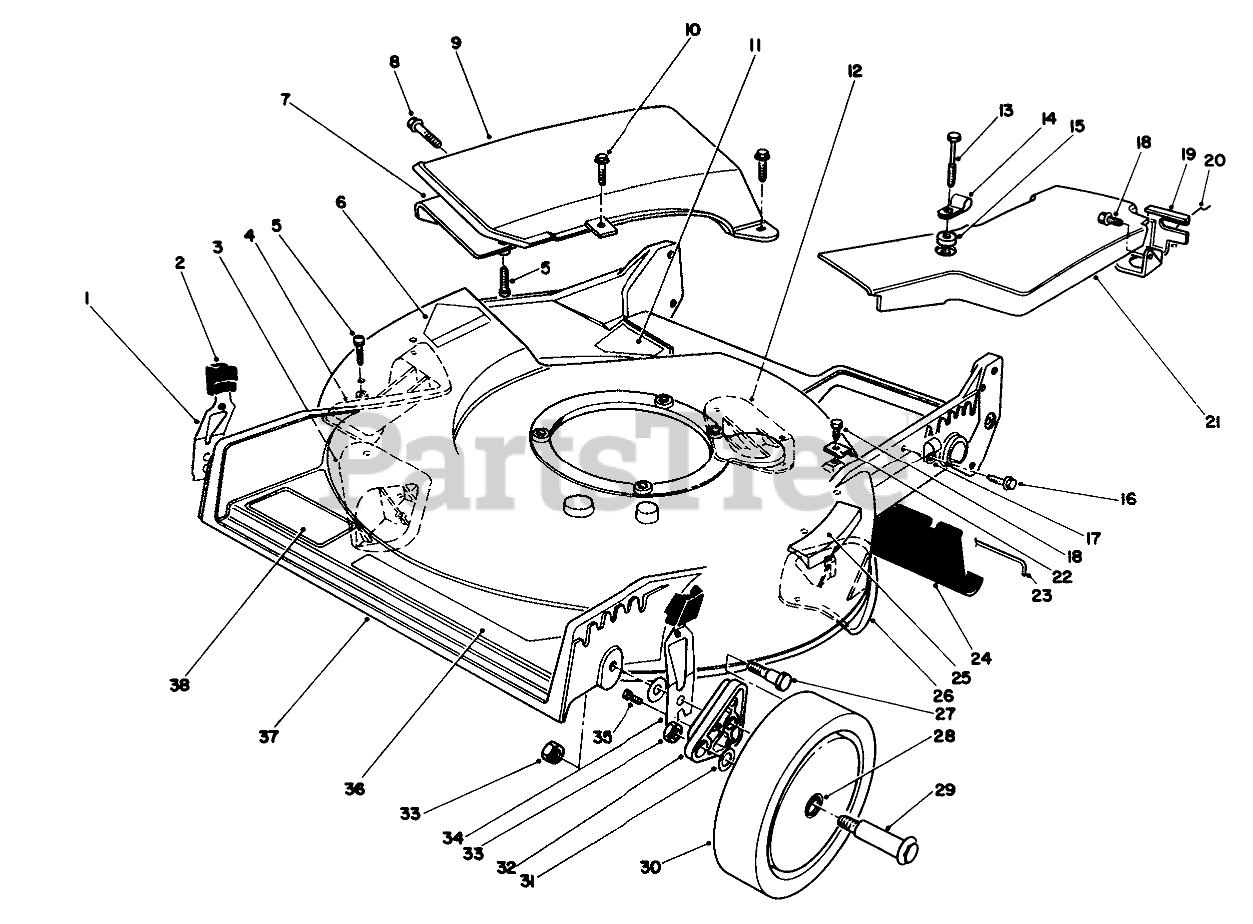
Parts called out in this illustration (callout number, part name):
1	RH SPRING ARM ASSEMBLY
2	KNOB-ARM
3	KICKER
4	KICKER
5	#8 X .625" PHILPS PAN H
6	DECAL-DANGER
7	Deflector
8	SCREW AND WASHER ASM
9	Cover-Recycler
10	SCREW-HWH
11	DECAL - DANGER
12	KICKER
13	SCREW-SPECIAL
14	CLAMP-CABLE
15	WASHER
16	SCREW
17	CLAMP-CABLE
18	SCREW-HWHTF
19	Bracket-Adj. Trac
20	RETAINER-CABLE
21	BELT COVER
22	CLAMP-CABLE
23	ROD-SHIELD
24	SHIELD-TRAILING
25	STEP PAD DECAL
26	KICKER
27	SCREW-SHOULDER
28	BUSHING
29	WHEEL BOLT
30	Wheel & Tire Assembly (Incl. Ref. #28)
31	WASHER
32	ARM-PIVOT, FRONT
33	Nut
34	LH SPRING ARM ASSEMBLY
35	SCREW-HWH
36	DECAL - DECK
37	Housing (Incl. Ref. #3-6, 12, 18 & 26)
38	DECAL
